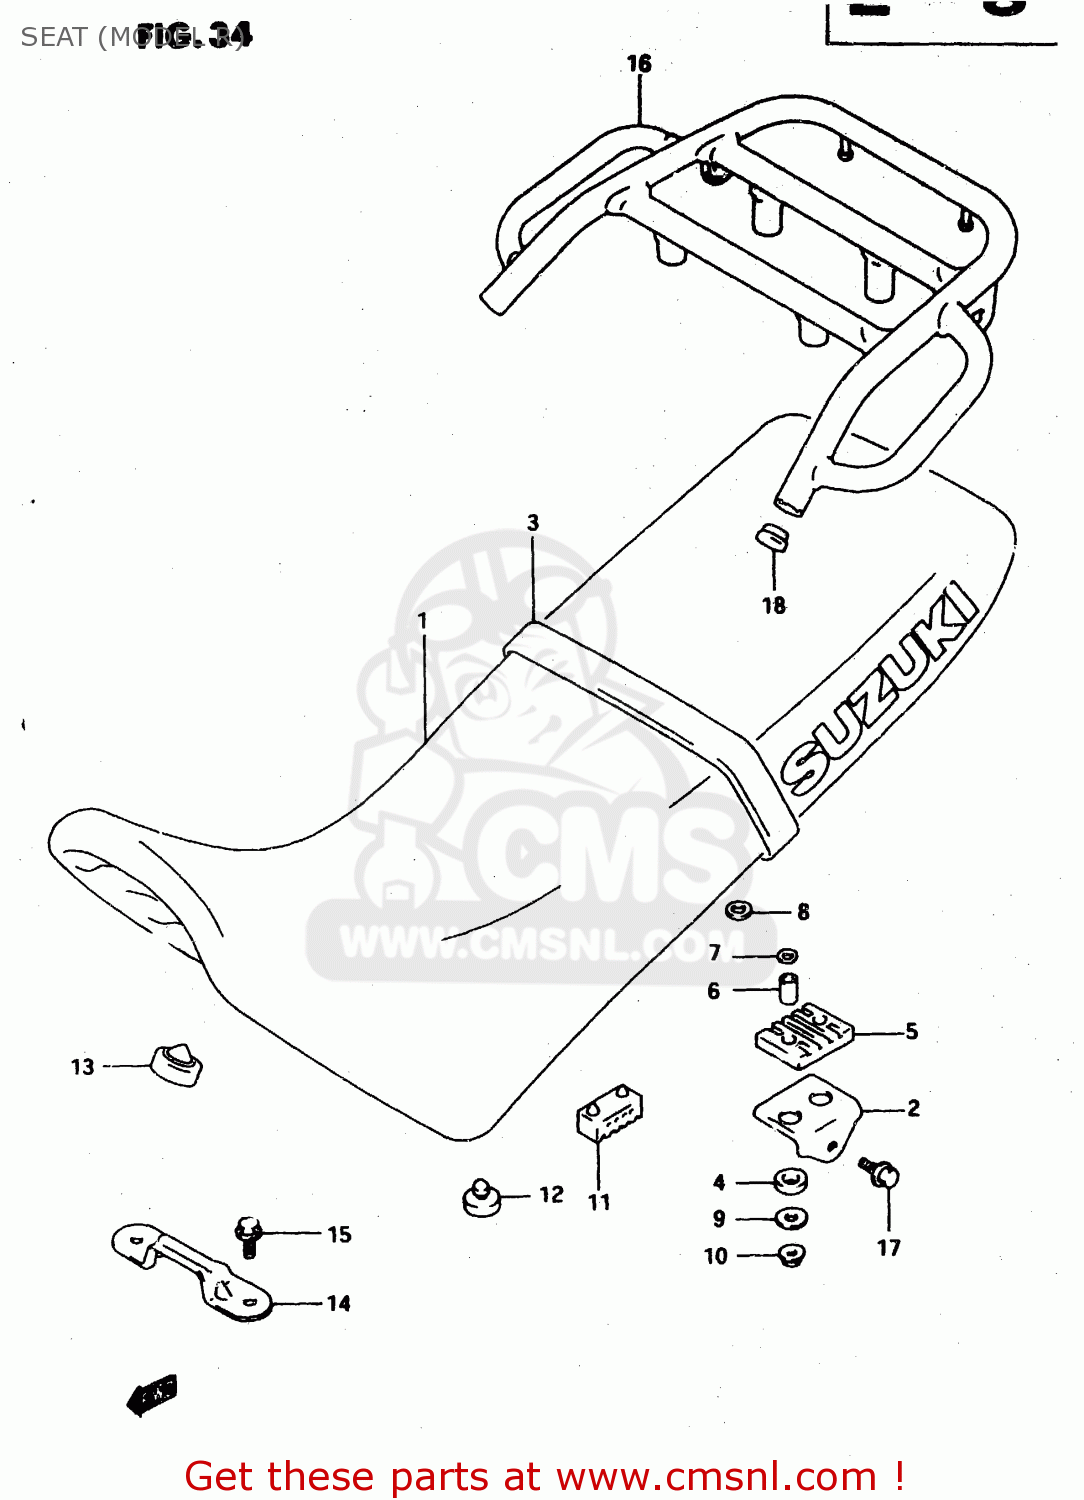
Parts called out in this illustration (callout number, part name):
1	SEAT SET
2	BRACKET,SEAT
3	BAND,SEAT
4	CUSHION,SEAT FR
5	CUSHION,FR PLATE
6	SPACER,SEAT BRACKET
7	WASHER
8	WASHER
9	WASHER
10	NUT
11	CUSHION,SEAT(40X20X15)
12	CUSHION
13	CUSHION,FRONT
14	PLATE,SEAT FR HOOK
15	BOLT
16	CARRIER,SPORT
17	BOLT
18	CAP(OD:19)
